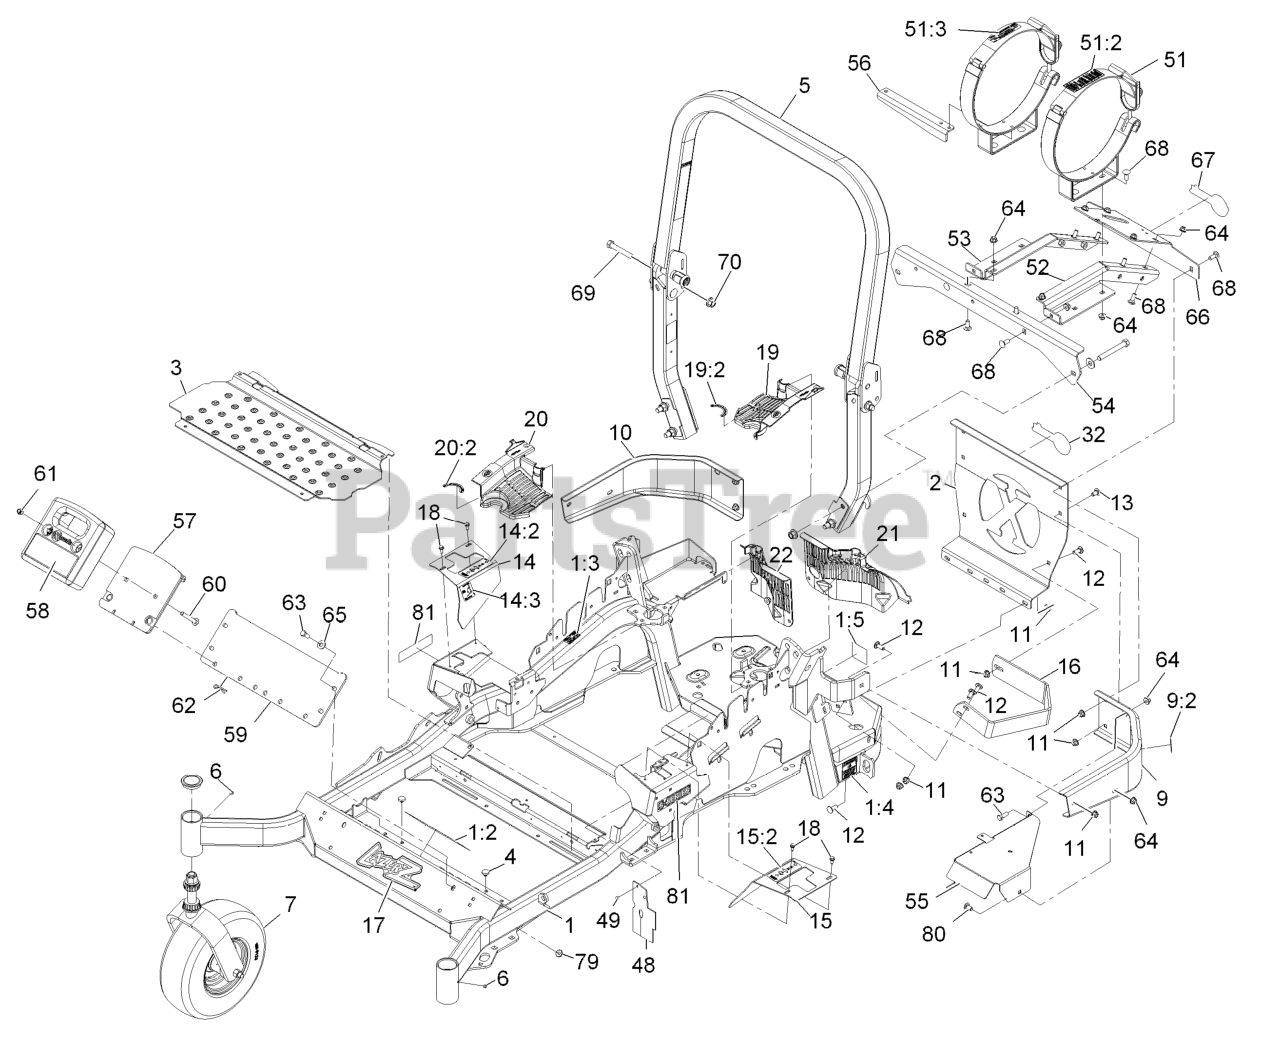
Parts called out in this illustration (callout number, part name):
1	MAIN FRAME ASM
1:2	DECAL-SLOPE
1:3	DECAL-CAUTION
1:4	DECAL-BELT DRIVE
1:5	DECAL-SPARK ARRESTER
2	PLATE,REAR GUARD
5	ROPS ASM
7	Asm,Front Caster W/Fork
9	LH BUMPER ASM
9:2	DECAL-CAUTION
10	BUMPER-RH
11	NUT-HF, NI
12	SCREW-CARR
13	SCREW-CARR
14:2	DECAL-MOTION CONTROL
15	LH MOTION CONTROL COVER ASM
15:2	DECAL-MOTION CONTROL
17	DECAL,LAZER MODEL
18	SCREW-HWH
19	LH HYDRO GUARD ASM
19:2	DECAL-HYDRO OIL
20	RH HYDRO GUARD ASM
20:2	DECAL-HYDRO OIL
21	GUARD-HYDRO, REAR (LH)
22	GUARD-HYDRO, REAR (RH)
48	DEFLECTOR-AIR FLOW
49	RIVET-POP
51	TANK BRACKET ASM (SET)
51:2	DECAL-LPG WARNING
51:3	DECAL-LPG 43.5LB TANK
52	LH LPG FRAME ASM
53	RH LPG FRAME ASM
54	SUPPORT-LPG FRAME, FRONT
55	PANEL-LPG, AC
56	PLATE-INDEX, LPG TANK
57	WLD,WEIGHT MOUNT
58	WEIGHT,CAST 36LB
59	PLATE,WEIGHT ASM MOUNT
60	SCREW-CARR
61	NUT-LOCK, NI
62	PIN-HAIR
63	SCREW-HH
64	NUT-HF, NI
65	WASHER-BELLEVILLE
66	SUPPORT-REAR FRAME, LPG
68	BOLT-CARR
69	SCREW-HH
70	Nut-Lock 1/2-13
79	NUT-HF, NI
80	SCREW-CARR
81	DECAL-S-SERIES
